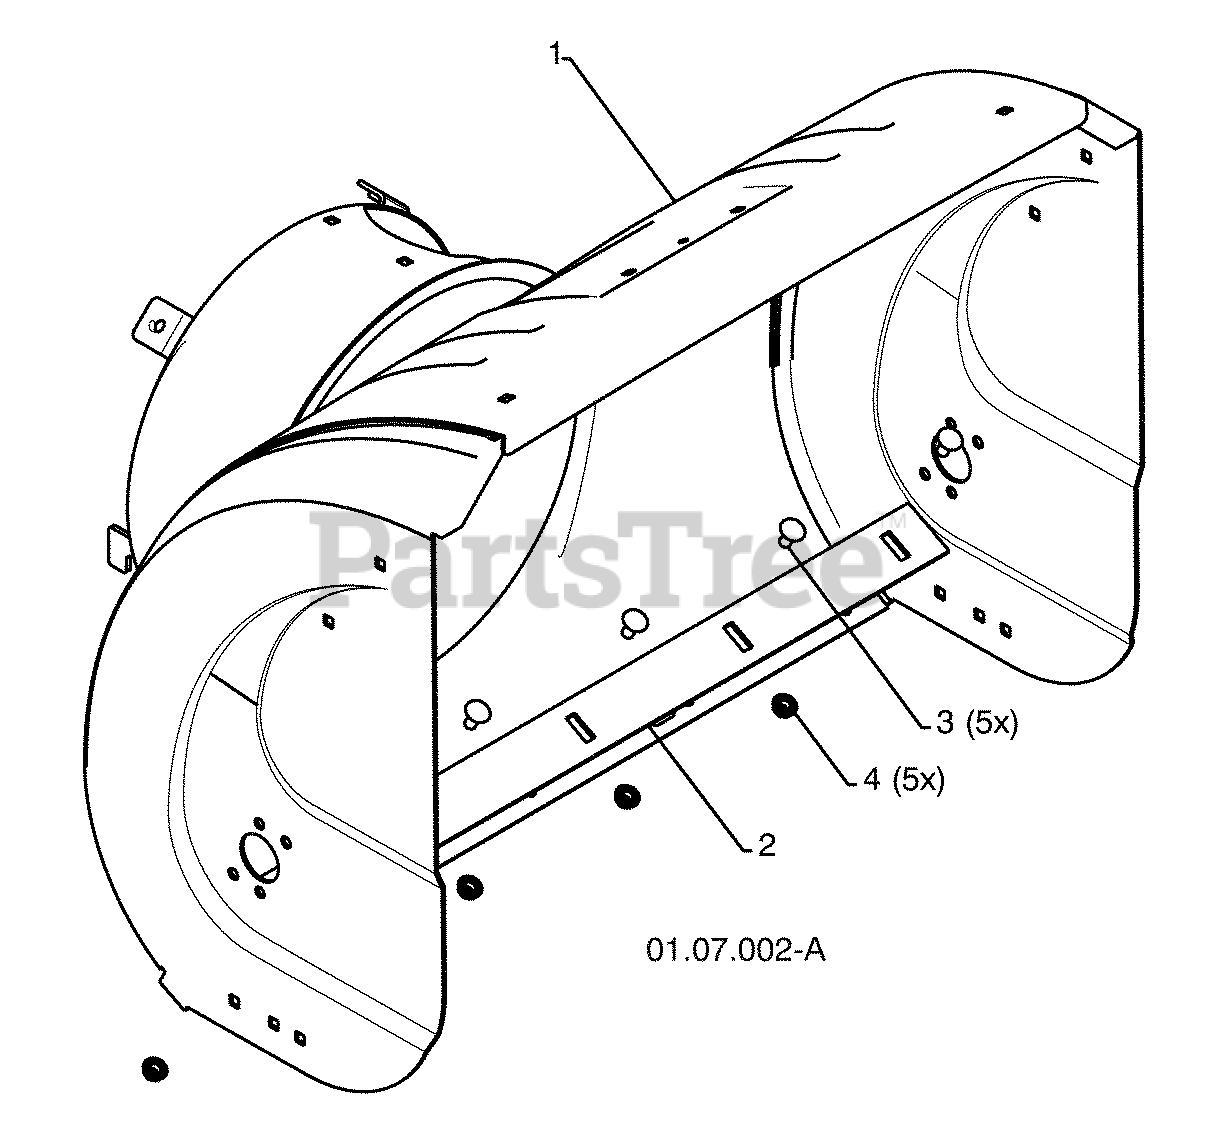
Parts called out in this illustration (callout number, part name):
1	AUGER HOUSING 27
2	SCRAPER BAR
3	CARRIAGE BOLT 5/16-18 X .625
4	NUT 5/16-18
